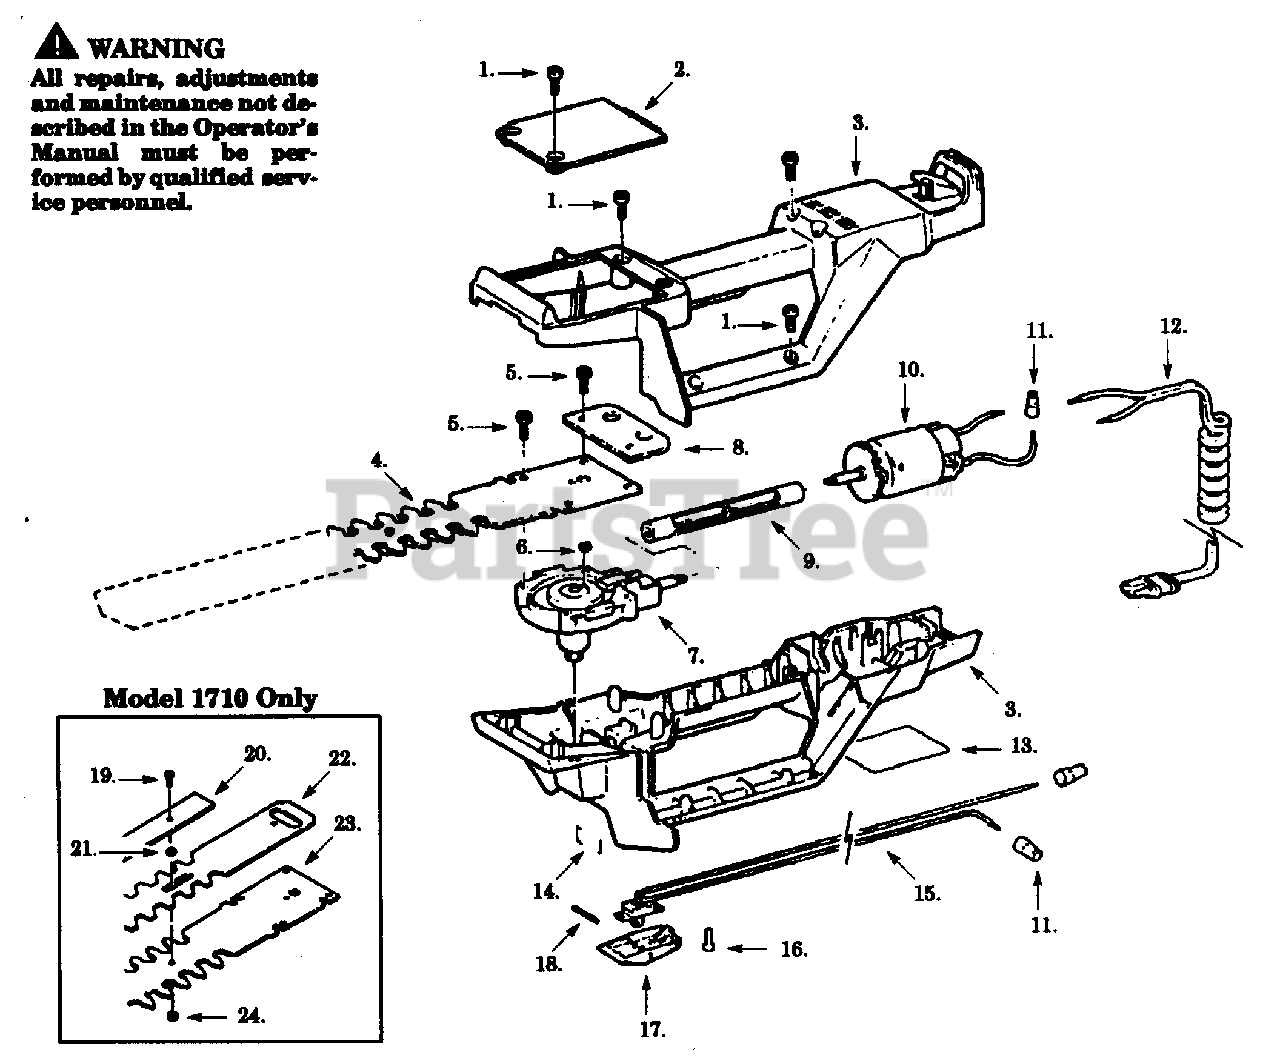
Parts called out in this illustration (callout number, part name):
2	Gear Box Cover
3	Housing Set
4	Blade Ass'y.
7	Gear Box Ass'y.
9	Drive Shaft
10	Motor/Fan Ass'y.
11	Wire Nut
12	Power Cord
13	Warning Label (Not a serviceable part)
14	Danger Label (Not a serviceable part)
15	Switch/Wire Ass'y.
17	Switch Cap
18	Groove Pin
20	Retaining Plate
22	Cutting Blade
23	Stationary Blade
